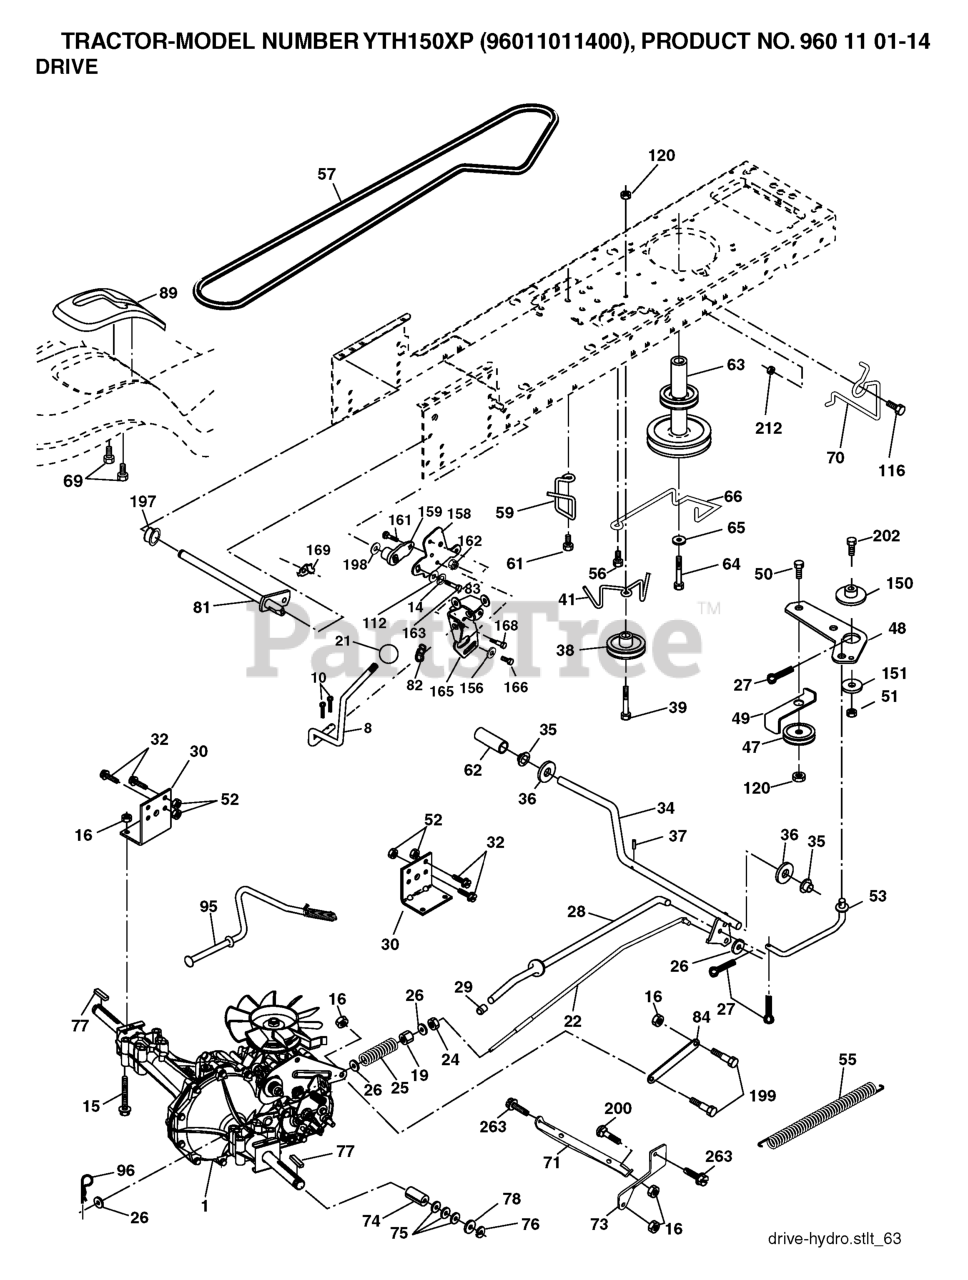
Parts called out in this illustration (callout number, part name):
8	ROD.SHIFT.FENDER.ADJ.STLT
10	PIN COTTER
14	LOCKWASHER
15	BOLT HEX 5/16-18 GR 5
16	NUT.71038.31-18.HEX.NYLOCK
19	NUT
21	KNOB.DUCKHEAD.1/2
22	ROD BRAKE HYDRO
24	NUT
25	SPRING ROD LT
26	WASHER
27	COTTER PIN
28	ROD, PARKING BRAKE
29	PLUNGER CAP
30	BRKT, TRNSXLE MNT 20"
32	BOLT
34	SHAFT, FOOT PEDAL
35	BEARING.NYLON
36	WASHER LT
37	DRIVE PIN
38	PULLEY IDLER COMPOSITE
41	KEEPER, BELT IDLER
47	IDLER PULLEY
48	BELLCRANK, CLUTCH
49	RETAIN BELT
50	BOLT.3/8-16X1.50
52	LOCKNUT
53	LINK.CLUTCH.7.66.2005
55	SPRING, RETURN LT
56	SCREW.3/8-16
57	DRIVE BELT, LTH & YTH TRACTORS
59	KEEPER, BELT CENTER
61	SCREW 3/8-16X.875
62	COVER, PEDAL (1 2)
64	BOLT HEX 7/16-20X4-1/4"
65	LOCKWASHER
66	KEEPER BELT ENGINE
69	SCREW.HI-LO.CONSOLE
71	STRAP TORQUE LH HYDRO
73	STRAP TORQUE RH HYDRO
74	SPACER AXLE
77	SQUARE KEY
81	SHAFT ASM CROSS TAPERED
82	SHIFT SPRING
83	WASHER
84	LINK TRANSAXLE
89	CONSOLE, SHIFT, STL, AUTO GREY
95	CONTROL ASM. BYPASS HYDRO
96	RETAINER M
112	WASHER LT
116	BOLT D
120	NUT LOCK FLG 3/8-16 UNC
150	SPACER, RETAINER
151	WASHER 12/32X2X10GA
156	WASHER.SRRTD.5/16
158	BRACKET
159	RB HUB.SHIFT
161	BOLT
162	NUT.CROWNLOCK.1/4
163	BOLT
165	RP BRACKET
166	CAPSCREW.HXHD.FLG.5/16-18X.625
168	BOLT.SHOULDER.5/16-18X
169	PLATE.FASTENING.CROSS.SHAFT
197	NYLINER SNAP 5/8" ID
198	WASHER.NYL.7/8IDX.105"HYD CR
199	BOLT SHOULDER 5/16-18 UNC
200	BOLT
212	NUT
263	SCREW, 3/8-16X3/4
